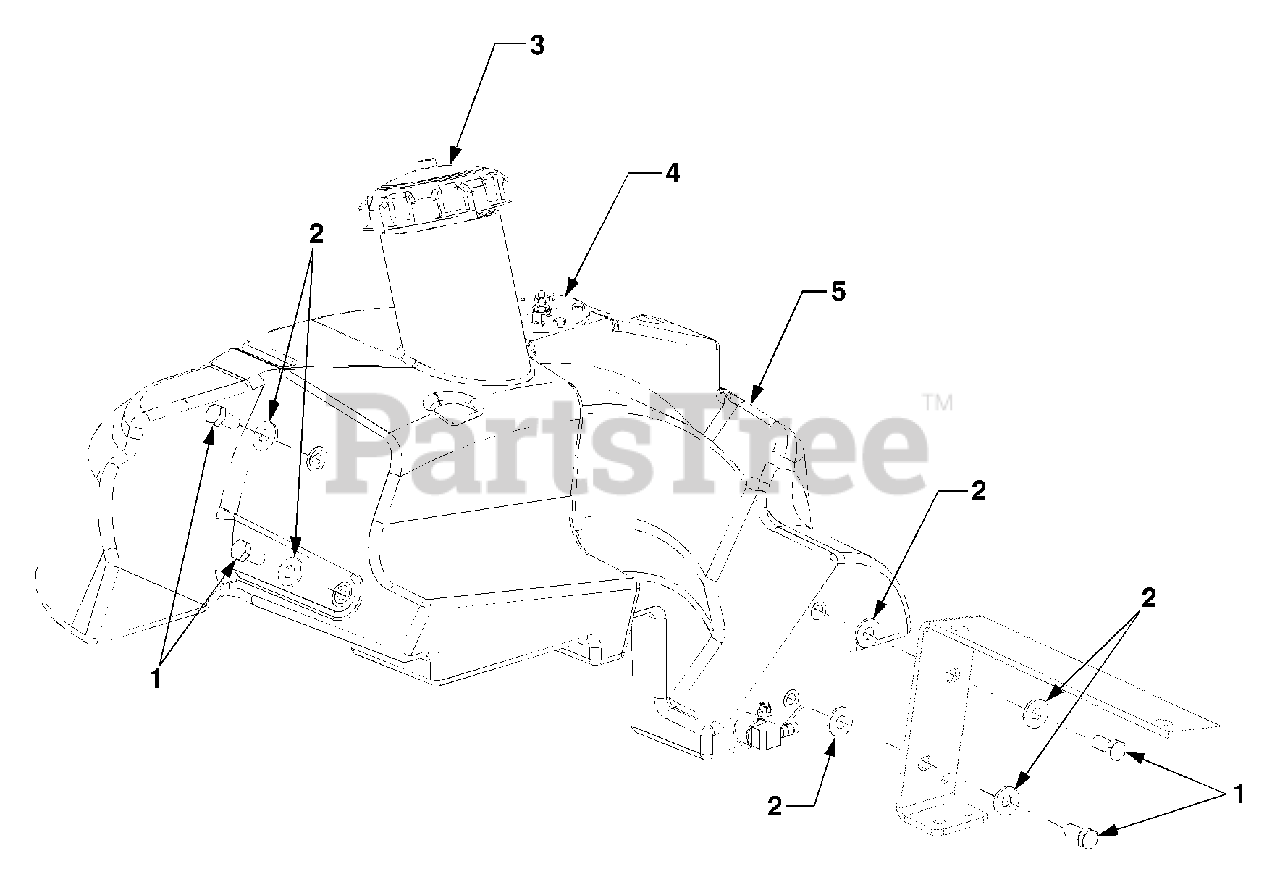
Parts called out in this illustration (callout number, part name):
1	Screw, Hex Cap, Lock 3/8-16 x .75 GR5
2	Washer, Flat, .385 x .87 x .092
3	Cap, Fuel
4	Sensor, Fuel Level
5	Tank, Fuel
